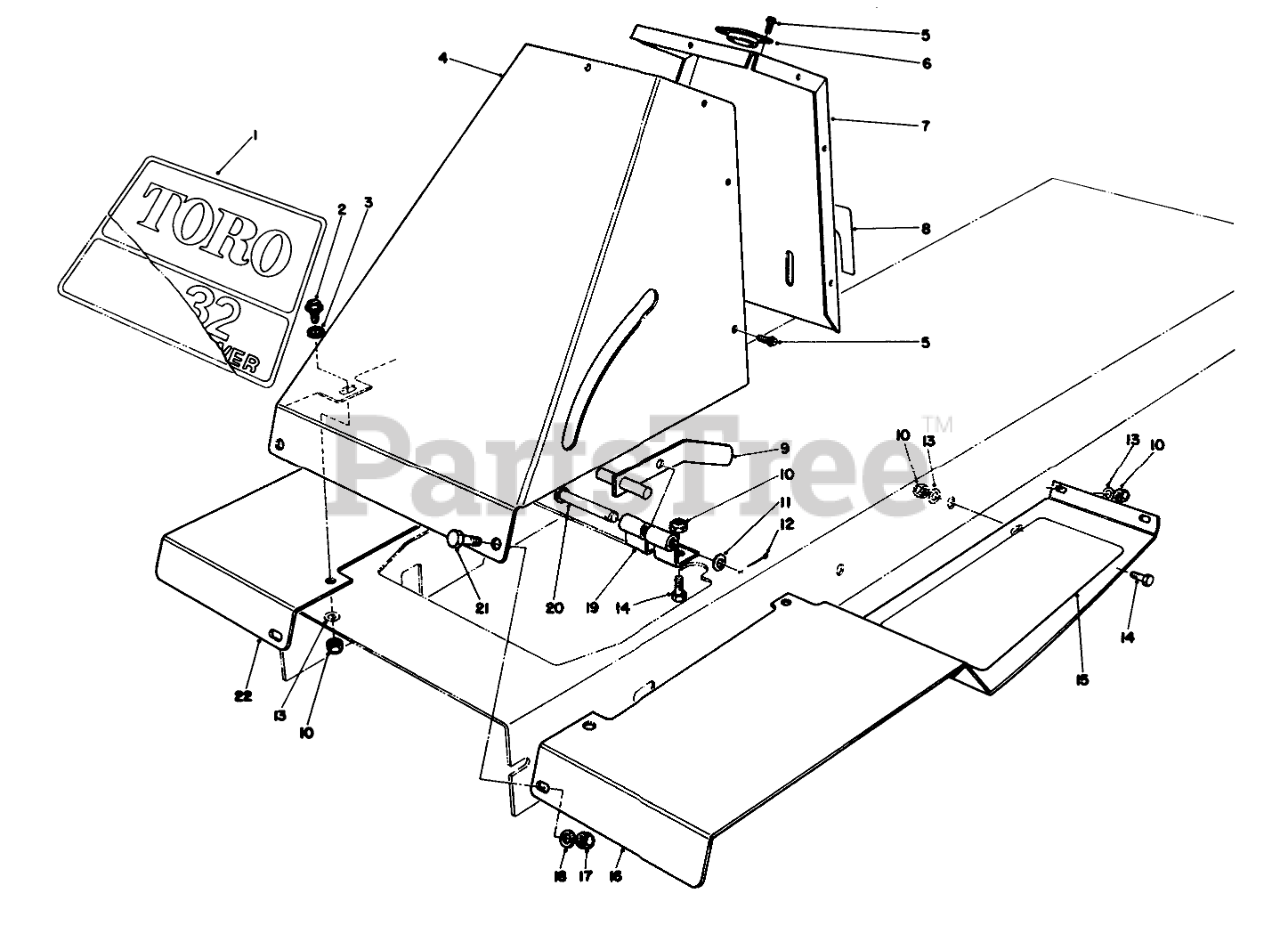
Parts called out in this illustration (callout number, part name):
1	Decal-Toro 832
2	SCREW-SHOULDER
3	SPACER
4	Tower-Front
5	SCREW-HWHTF
6	GUIDE-STRG SHAFT
7	Tower-Rear
8	PARK BRAKE DECAL
9	PARKING BRAKE WA B
10	NUT-LOCK, NI
11	WASHER-FLAT
12	PIN-COTTER
13	WASHER-PLAIN
14	SCREW-HH
15	FOOT TREAD L.H.
16	Footrest-LH
17	NUT-LOCK, CONE
18	WASHER-FLAT
19	Bracket-Parking Brake
20	PIN-CLEVIS
21	SCREW-HH
22	Footrest-RH.
